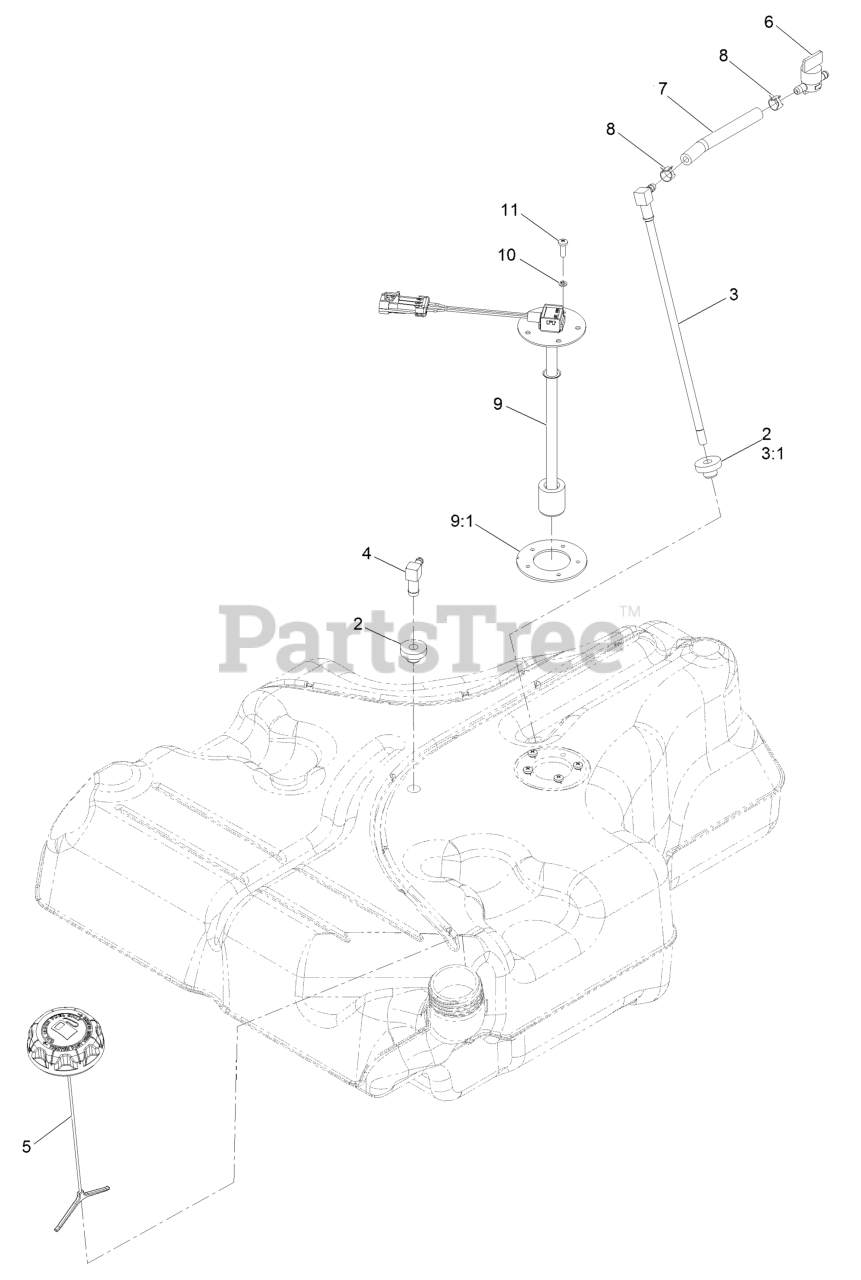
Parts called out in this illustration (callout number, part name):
2	Bushing
3	Fuel Line Kit (With Grommet)
3:1	Bushing
4	Fitting-90 Elbow
5	Cap-Fuel, Ratcheting
6	Valve-Fuel
7	Hose-Fuel
8	Clamp-Hose
9	Sender-Fuel Level W/Gasket 8 Gallon
9:1	Gasket-Sender
10	Washer-Lock 3/16
11	Screw-PPH #10-24 X 5/8
